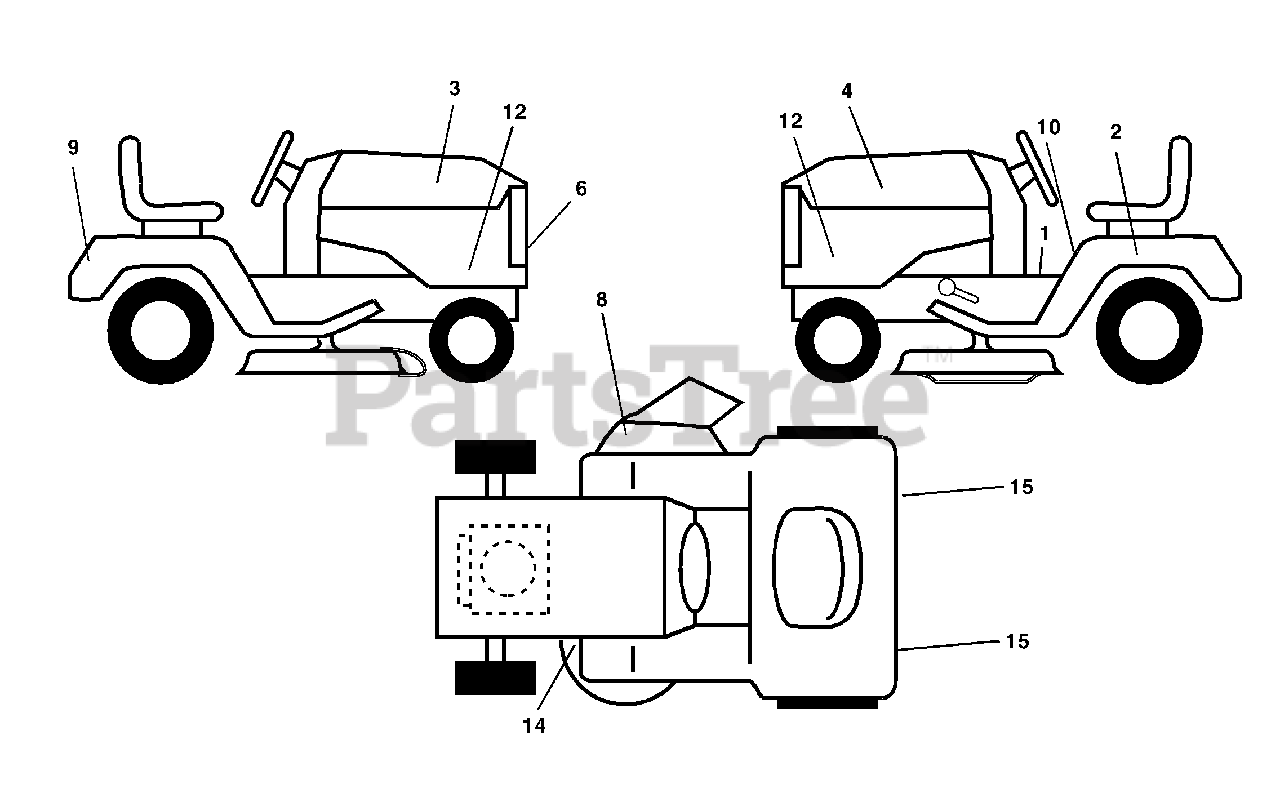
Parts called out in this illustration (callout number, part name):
1	Decal Oper. Step Thru E/F
2	Decal Battery
3	Decal Hood RH
4	Decal Hood LH
6	Decal Grille
8	Decal Warning
9	Decal Fender Husq
10	Decal Fender Danger E/F
12	Decal Hood Logo
14	Decal V-Belt Schematic
15	Reflector Tail Light
